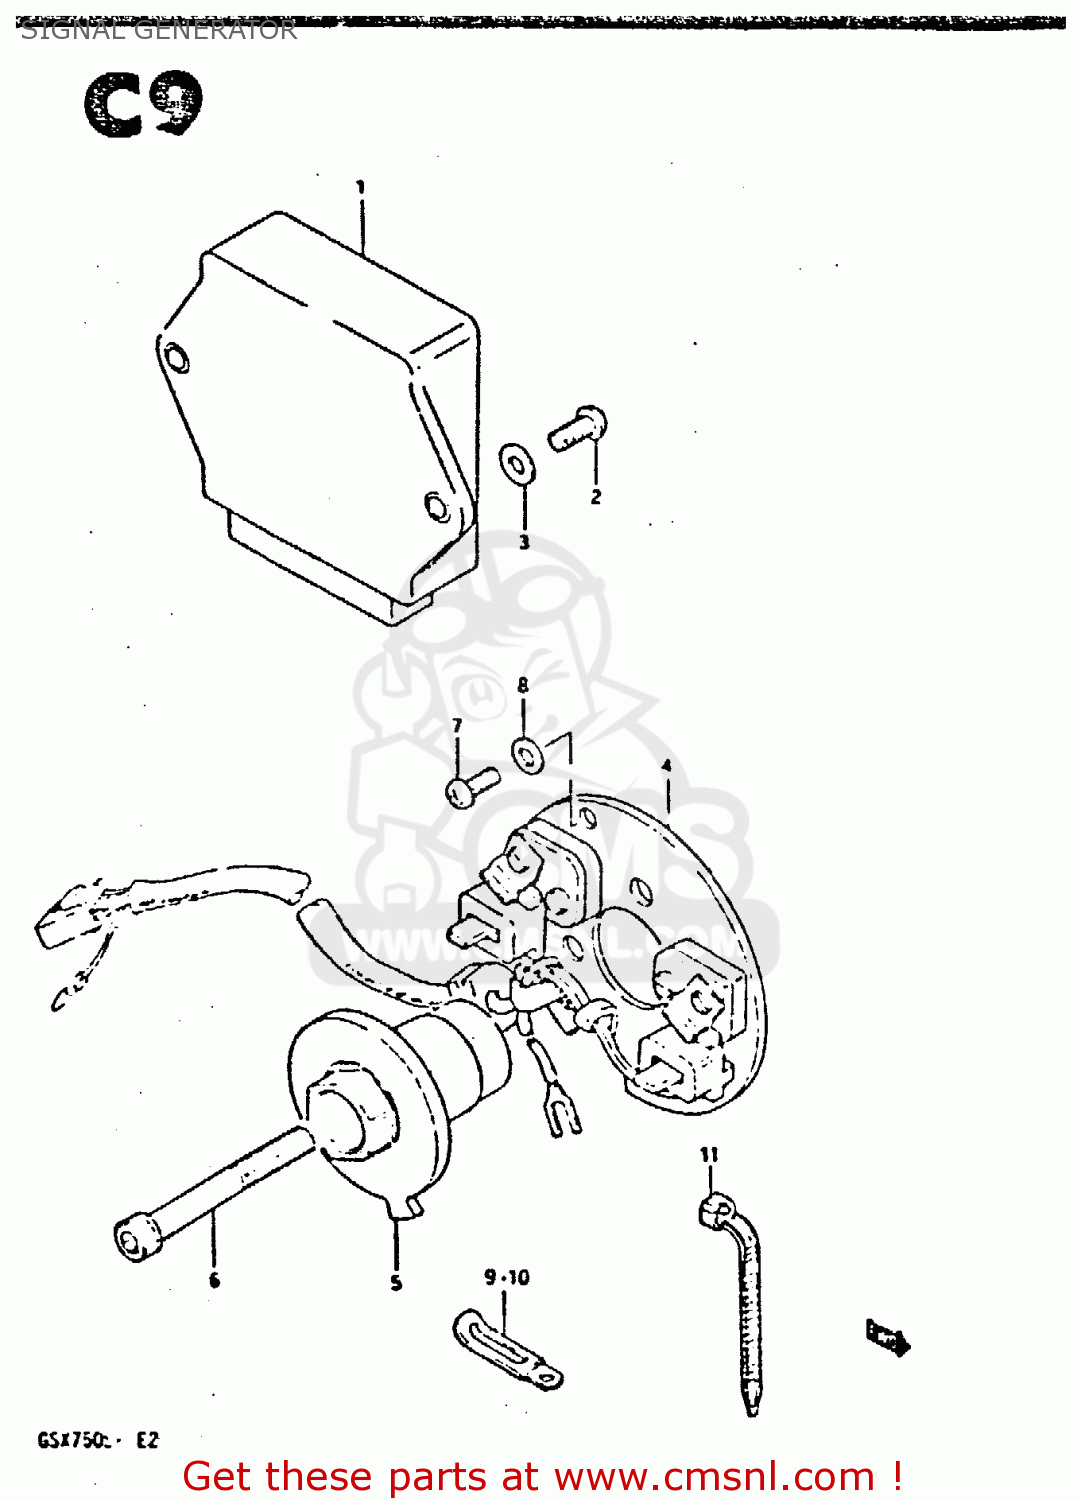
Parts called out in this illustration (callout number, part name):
1	IGNITER UNIT ASSEMBLY
2	SCREW
3	WASHER, LOWER
4	STATOR,SIGNAL GENERATOR
5	ROTOR,SIGNAL
6	BOLT
7	SCREW(5X12)
8	WASHER(5.5X10X0.8)
9	CLAMP
10	CLAMP
11	CLAMP(L:125)
